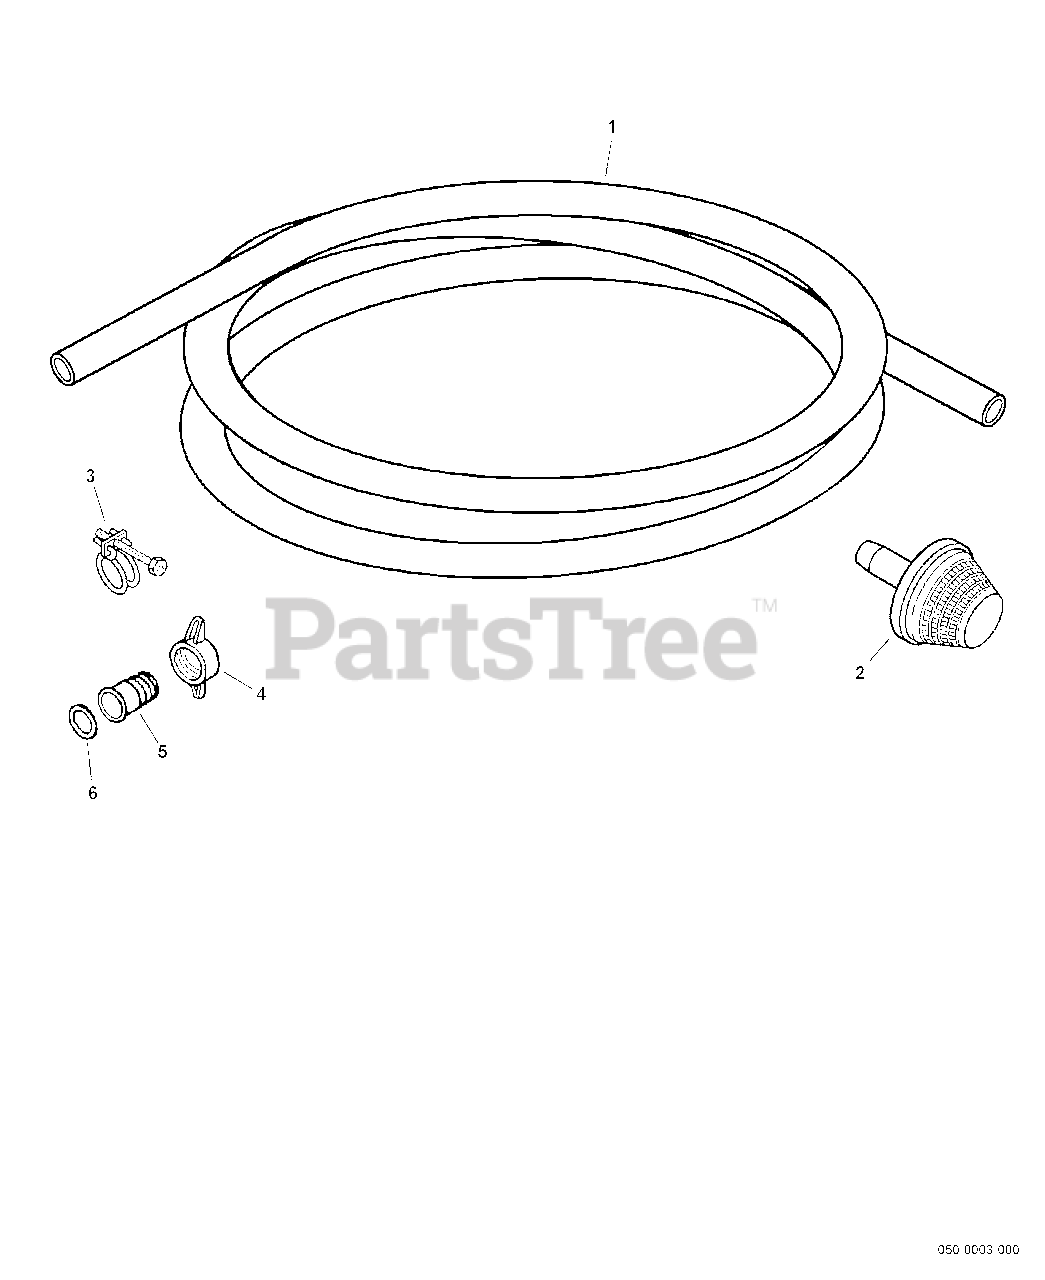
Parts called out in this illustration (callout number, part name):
1	HOSE, SUCTION - 1"×10'
2	STRAINER, DEBRIS
3	CLAMP, HOSE
4	NUT, HOSE
5	COUPLING, HOSE
